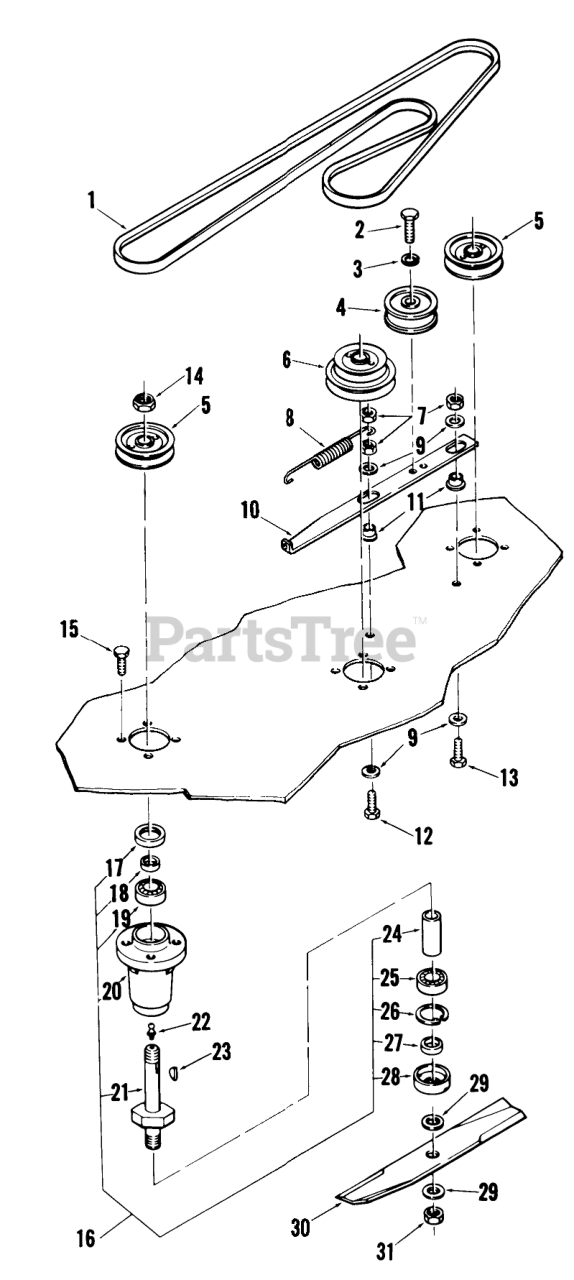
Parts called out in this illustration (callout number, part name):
1	V-BELT
5	PULLEY-BLADE DRIVE
6	PULLEY-48 MOWER SPDL
6	PULLEY-42 MOWER SPDL
8	SPRING-EXTENSION
9	WASHER
10	BAR-IDLER SUPPORT
18	SPACER-SEAL
19	BEARING-BALL
23	Hi-Pro Key 3/16 x 5/8
24	SPACER
25	BEARING-BALL
26	Ring-Snap
27	SPACER-BLADE
30	BLADE KIT (3 PACK)
